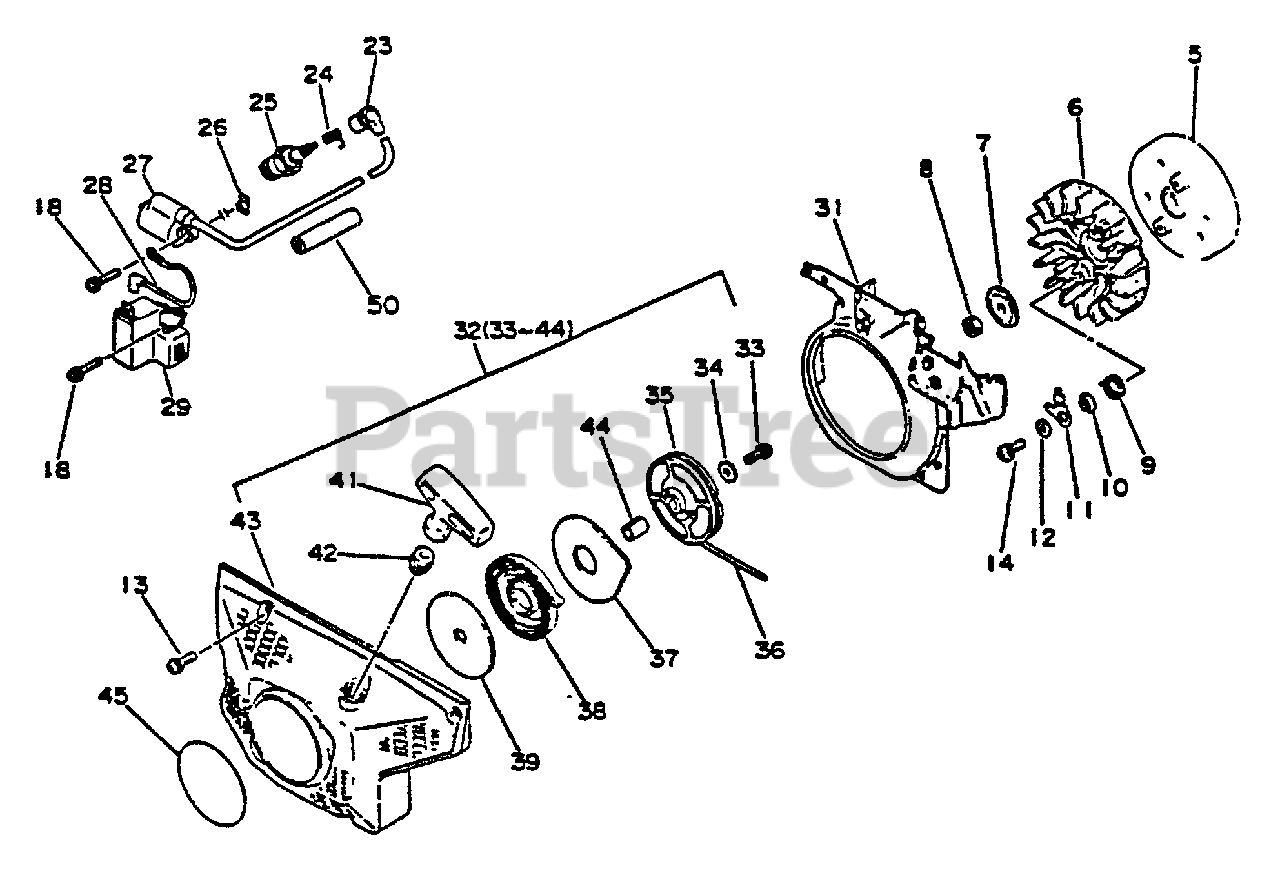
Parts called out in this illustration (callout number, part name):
5	FLYWHEEL
6	FAN
7	WASHER - CUP
9	SPRING, RETURN
10	SPACER
11	PAWL, STARTER
12	WASHER - 5
13	SCREW - 5X20
14	SCREW - 5X25
18	SCREW - 4X20
23	CAP, SPARK PLUG
24	TERMINAL, SPARK PLUG CAP
25	SPARK PLUG -- BPM-7A
27	COIL, IGNITION
29	COIL, IGNITION
31	SHIELD, FAN
32	STARTER ASSY
33	SCREW - 5X14
34	WASHER - 5
35	REEL, ROPE
36	ROPE, STARTER - 4X950
37	PLATE, STARTER
38	SPRING, REWIND
39	PLATE, STARTER
41	GRIP, STARTER
42	GUIDE, ROPE
43	CASE, STARTER
45	LABEL - ECHO
50	TUBE
